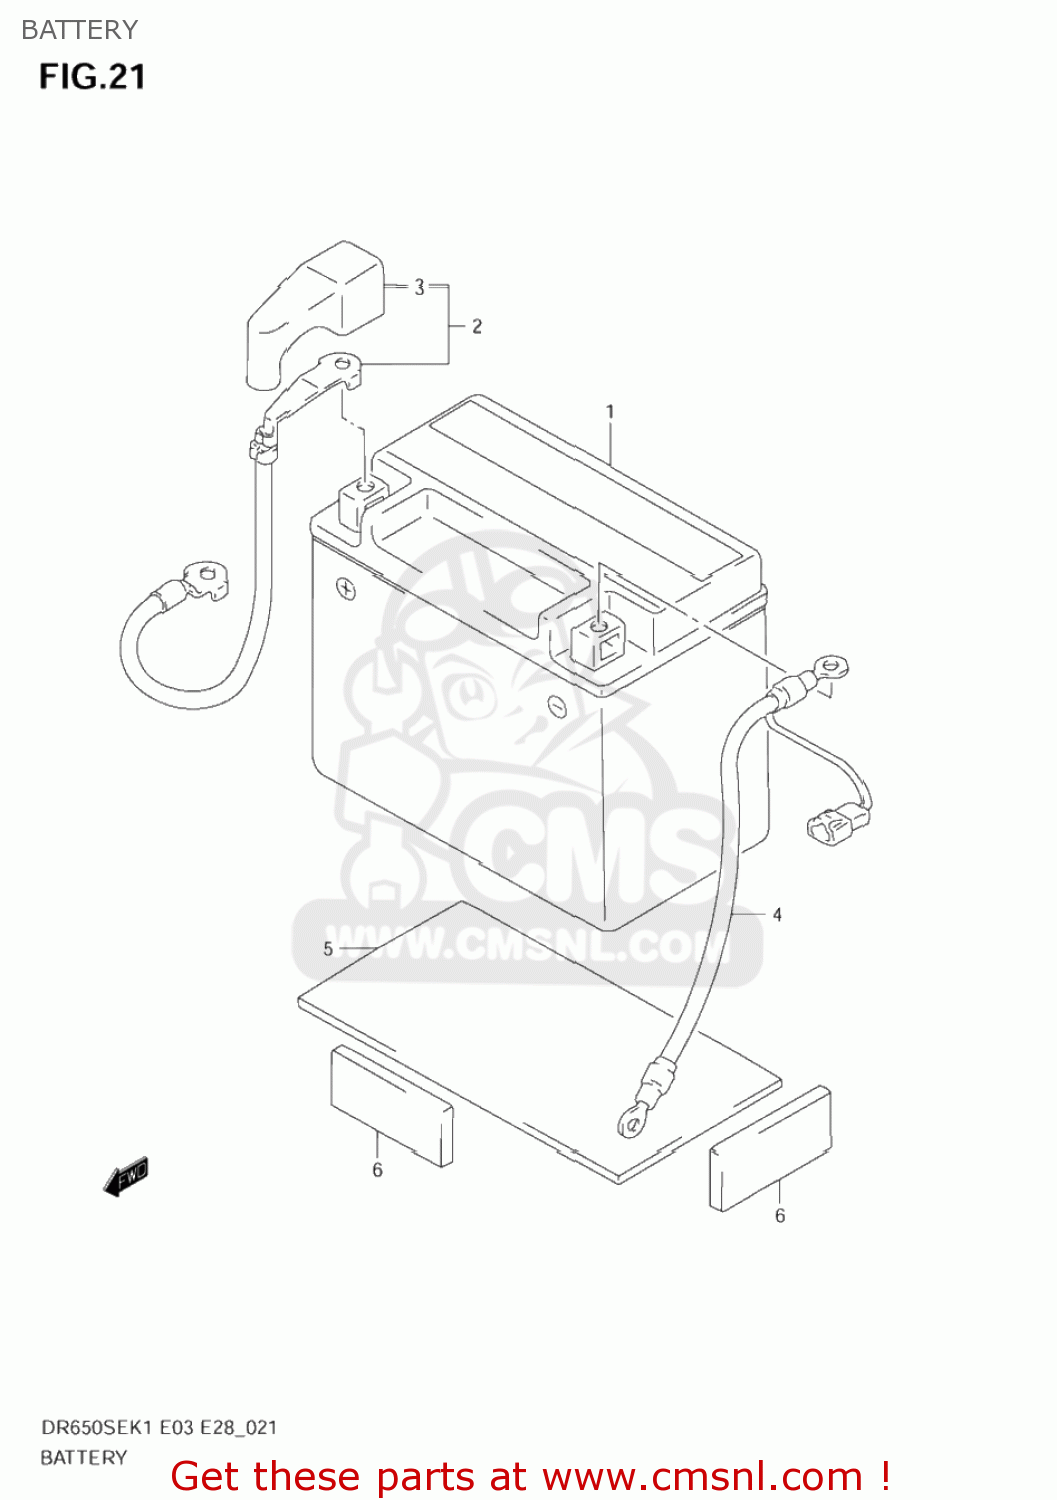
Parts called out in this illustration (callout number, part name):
1	BATTERY ASSY(YTX9-BS,12V8AH)
2	WIRE,BATTERY PLUS
3	CAP,BATTERY PLUS TERMINAL
4	WIRE,BATTERY MINUS
5	PROTECTOR(170X95X3.0)
6	CUSHION 20X45X6
